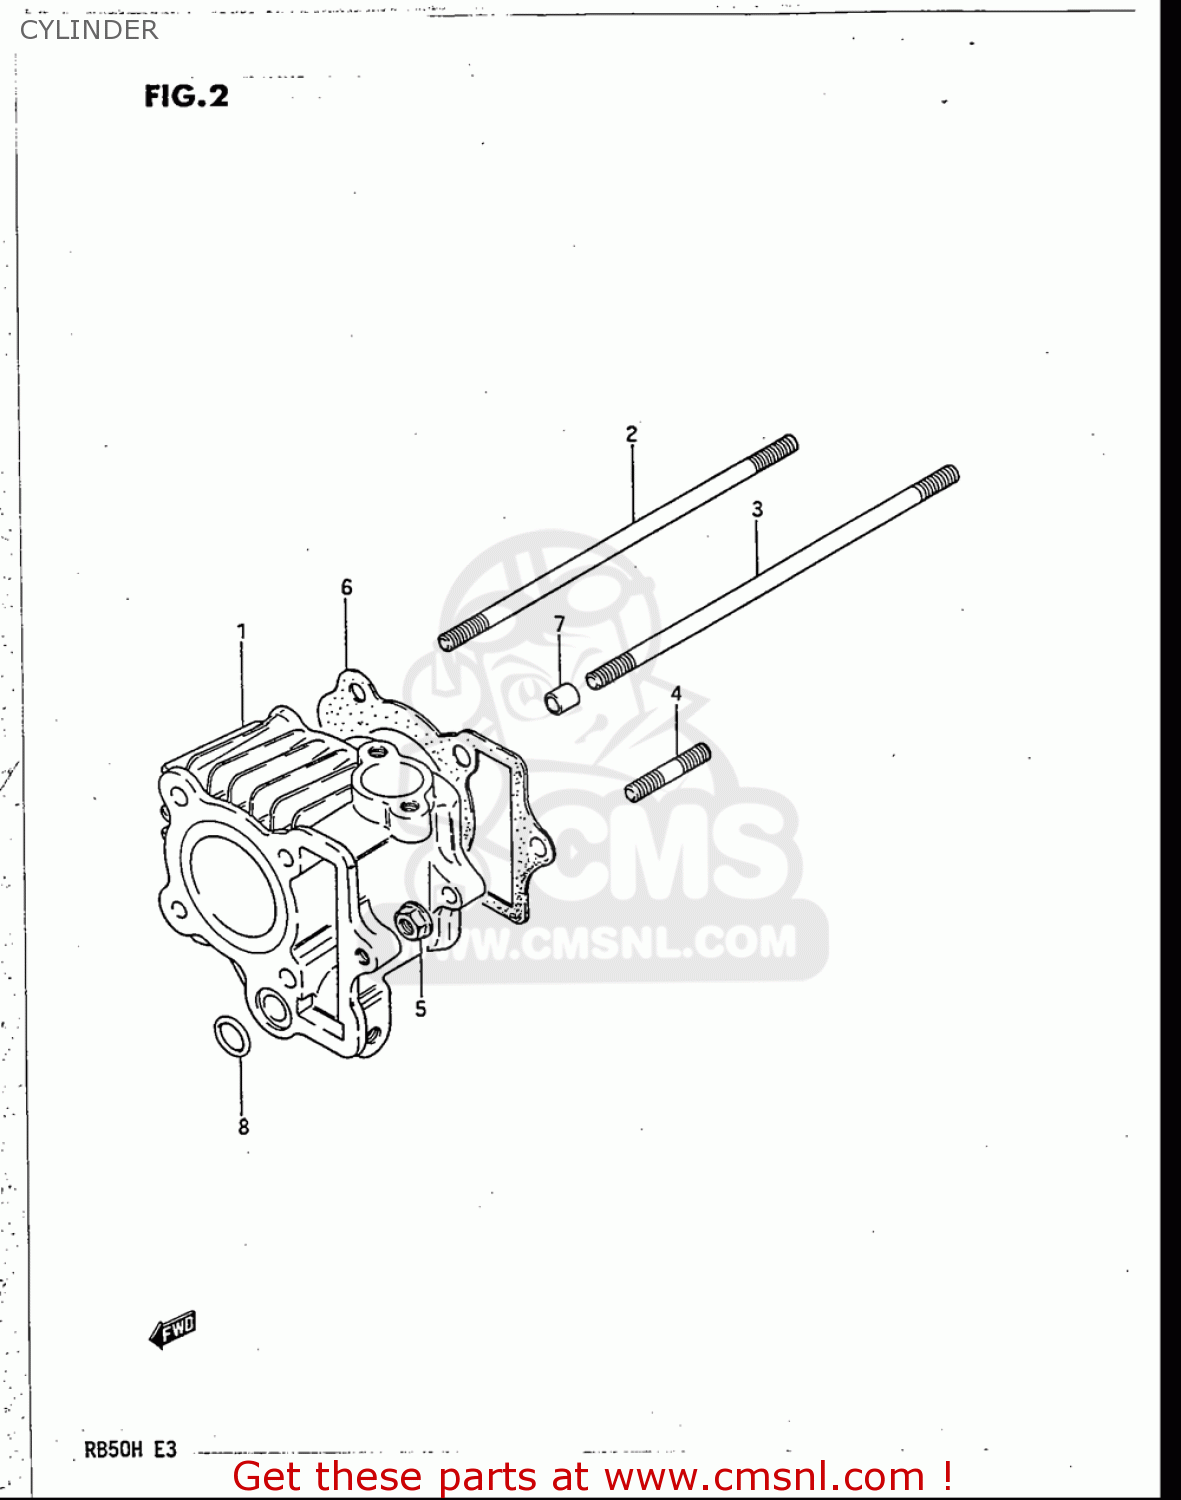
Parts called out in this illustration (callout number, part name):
1	CYLINDER
4	BOLT,STUD
5	NUT
6	GASKET,CYLINDER (NAS)
7	PIN(6.2X8X11)
8	O RING(D:2.4,ID:11.8)
